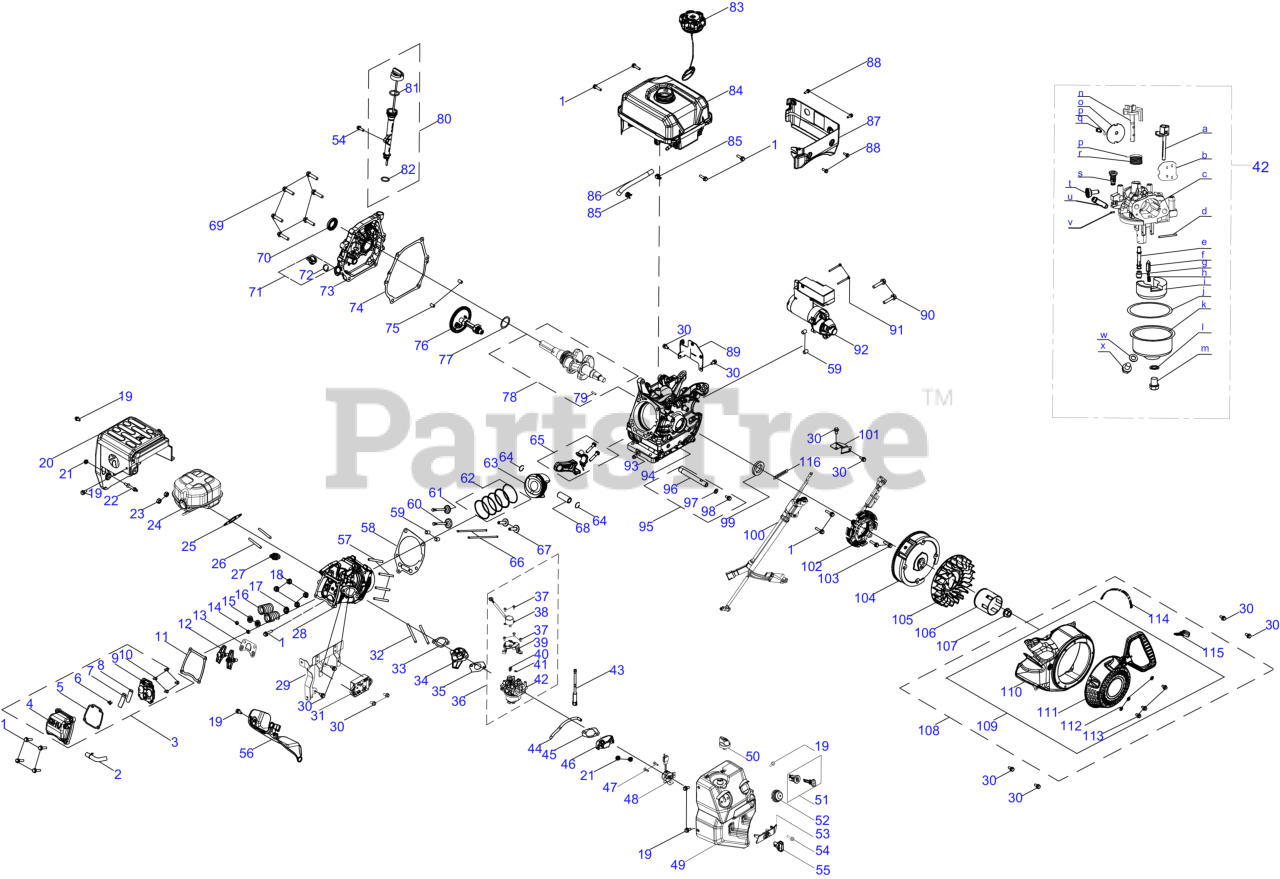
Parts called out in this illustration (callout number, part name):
1	BOLT M6-1 x 25 GR8.8
2	BREATHER HOSE
3	Not Serviceable/ Components Only
4	VALVE COVER
5	VALVE COVER GASKET
6	SCREW M3x8
7	BREATHER PLATE
8	BREATHER VALVE
9	INNER VALVE COVER
10	SCREW M5x12
11	VALVE COVER GASKET
13	ROCKER ARM BASE
14	VALVE CLIP
15	VALVE SPRING SEAT
16	VALVE SPRING
17	INTAKE VALVE SEAL
18	NUT M8
19	BOLT M6-1 x 14 GR8.8
20	MUFFLER GUARD
22	STUD, M6x55
25	MUFFLER GASKET
27	SPARK PLUG (F6RTC/RN11YC/BPR6ES)
28	CYLINDER HEAD
29	SNOW GUARD
30	BOLT M6-1 x 12 GR8.8
32	STUD M6-1 x 98
33	CARB INSULATOR GASKET
35	CARBURETOR GASKET
36	CARBURETOR
37	SCREW M4x8
38	STEPPER EGOV MOTOR
39	MOTOR BASE
40	CARBURETOR DAMPER
41	DAMPER SPRING
42	CARBURETOR
43	CHOKE LINKAGE
44	PRIMER HOSE
45	AIR FILTER GASKET
46	HEATER BOX
48	SPEED CONTROL SWITCH
49	CONTROL PANEL
50	CHOKE LEVER
51	ENGINE KEY SWITCH ASSEMBLY
53	SPEED KNOB COVER
54	BOLT M6-1 x 18 GR8.8
55	SPEED CONTROL KNOB
56	ENGINE SHROUD
57	STUD M8x60
58	CYLINDER HEAD GASKET
60	INTAKE VALVE
61	EXHAUST VALVE
62	PISTON RING SET 75MM
64	PISTON PIN SNAP RING
65	CONNECTING ROD
69	BOLT M8x35
72	O-RING 15.8 x 2.5
73	CRANKCASE COVER
74	CRANKCASE GASKET
77	THRUST WASHER
78	CRANKSHAFT
79	WOODRUFF KEY
85	CARBURETOR HOSE CLAMP
87	FUEL TANK COVER
88	Bolt, M5×14
89	DIPSTICK BRACKET
90	BOLT, M8x40
92	ELECTRIC STARTER
93	OIL DRAIN PLUG
95	Not Serviceable/ Components Only
96	OIL DRAIN PIPE
97	WASHER
98	OIL DRAIN PLUG
100	IGNITION MODULE
101	WIRE BOARD
102	CHARGING COIL
103	BOLT-M6-1 x 28 GR8.8
105	COOLING FAN
106	STARTER CUP
107	FLYWHEEL NUT
108	Not Serviceable/ Components Only
109	Not Serviceable/ Components Only
110	BLOWER HOUSING
111	RECOIL STARTER ASSEMBLY
112	FLAT WASHER
113	BOLT M6 x 10
114	CABLE TIE - 3 x 150
115	IGNITION KEY
